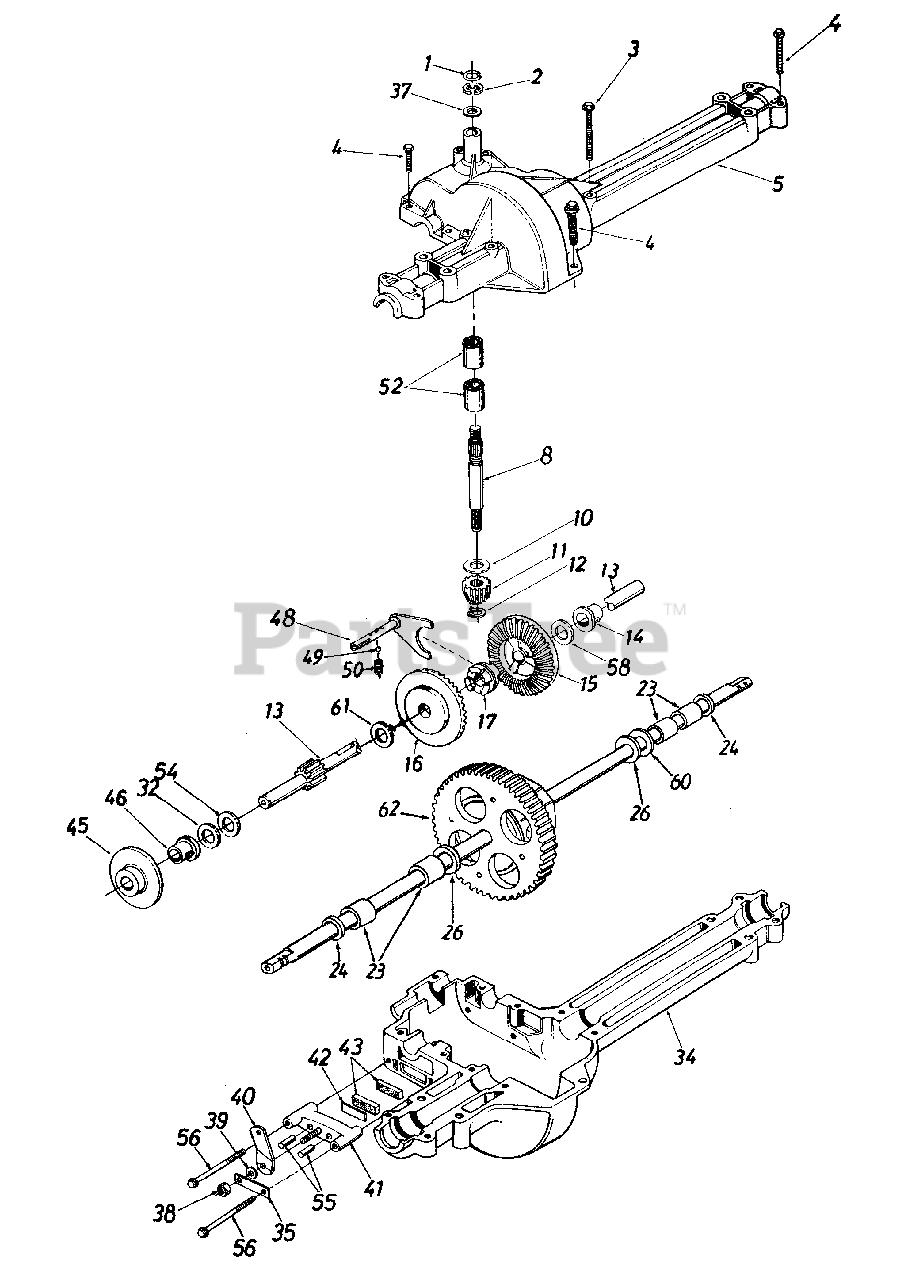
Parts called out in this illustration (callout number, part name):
1	Wire Ring
2	"O"-Ring
3	Hex Wash. TT-Tap 1/4-20 x 1.625" L
4	Hex Tap Scr. 1/4-20 x 1.25" Lg.
5	Upper Housing
8	Input Shaft
10	Thrust Wash. 5/8" I.D. x 1.25" O.D.
11	Pinion Input 14T
12	Retaining Ring
13	Drive Shaft-L.H. Brake
14	Flange Brg. 5/8" I.D. x 3/4" Lg.
15	Bevel Gear 42T-Small I.D.
16	Bevel Gear 42T-Large I.D.
17	Clutch Collar
23	Sleeve Bearing 3/4" I.D. x 1.0" Lg.
24	Oil Seal 3/4" I.D.
26	Axle Spacer
32	Thrust Wash. 5/8" I.D. x 1" O.D. x .025" Thk.
34	Lower Housing
35	Anti-Rotation Brkt.
37	Fl-Wash. 5/8" I.D. x 1" O.D. x .020" Thk.
38	Hex Nut 5/16-24 Thd.
39	Fl-Wash. .344" I.D. x .875" O.D.
40	Actuating Arm
41	Brake Yoke
42	Puck Plate
43	Brake Puck
45	Brake Disc
46	Flange Bear. 5/8" I.D. x 15/16" Lg.
48	Shift Fork Ass'y.
49	Ball Detent .250" Dia.
50	Spring Detent
52	Needle Brg. 5/8" I.D. x 1/2" Lg.
54	Fl-Wash. 5/8" I.D. x 1" O.D. x .020 Thk
55	Actuating Pin 5/16" Dia.
56	Hex Wash Hd. Self-Tap Scr. 1/4-20 Thd.
58	Fl-Wash. 5/8" I.D. x 1" O.D. x .020" Thk.
60	Fl-Wash. .76" I.D. x 1.5" O.D. x .010" Thk.
61	Thrust Washer
62	Differential Ass'y.
7360445	Fl-Wash. .76" I.D. x 1.5" O.D. x .060" Thk.
